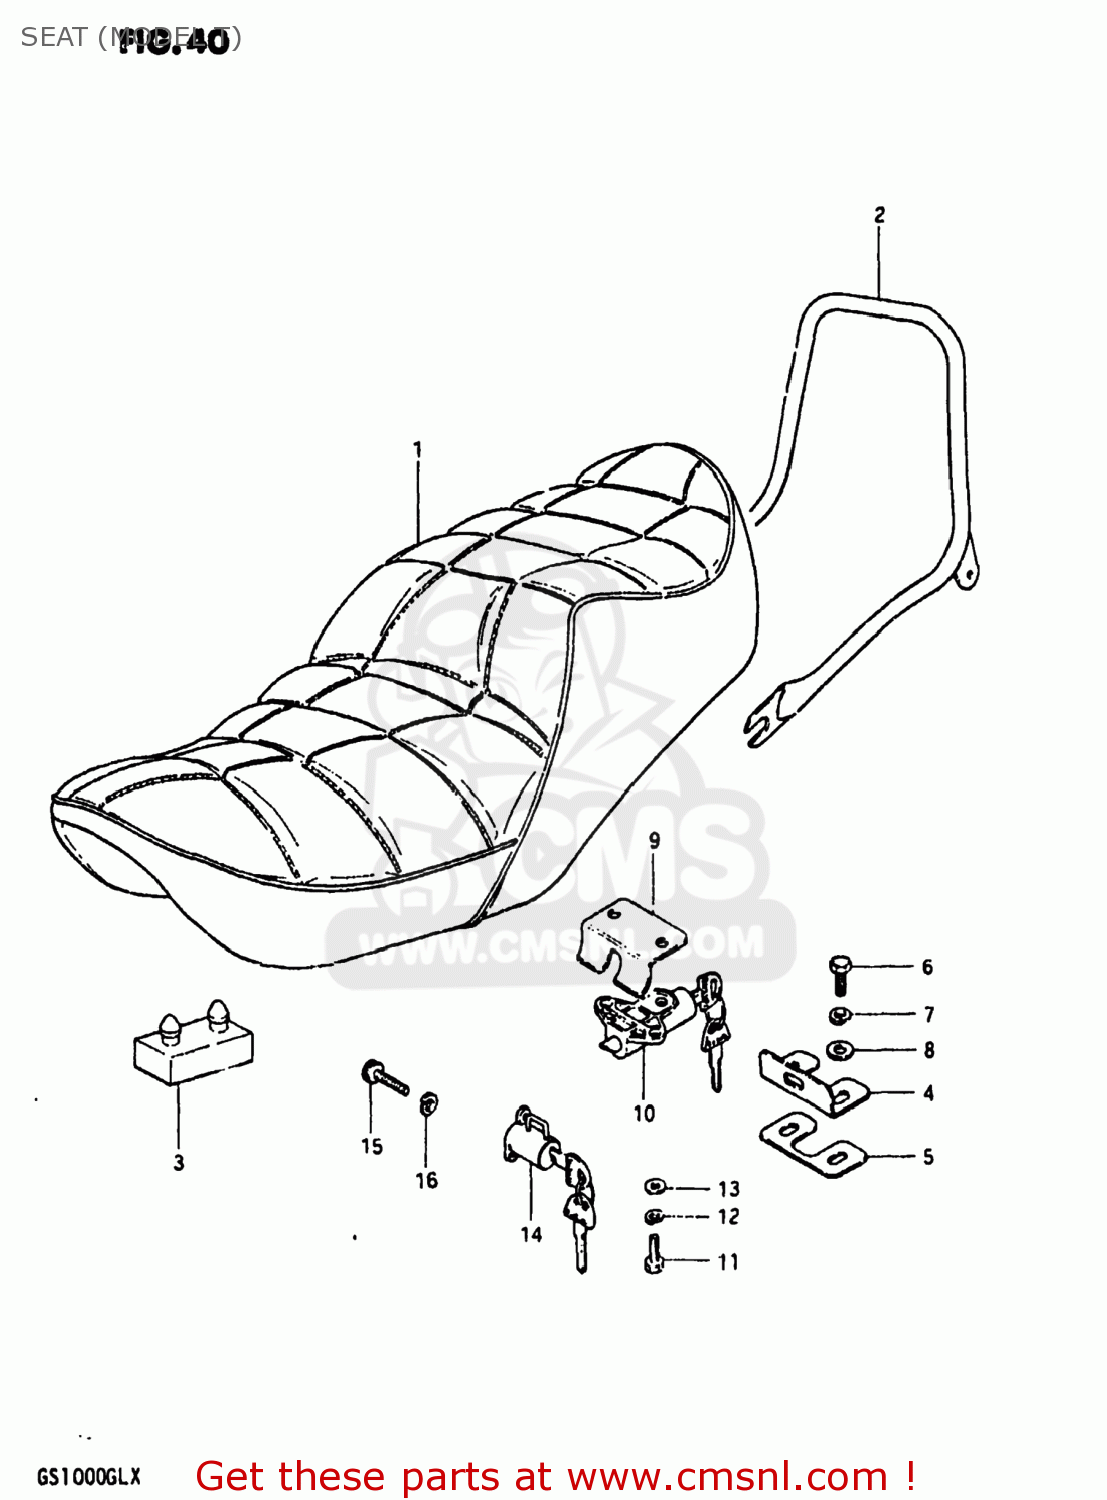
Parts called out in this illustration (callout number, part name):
1	SEAT ASSEMBLY
2	HANDLE,PILLION RIDER
3	CUSHION
4	STRIKER,SEAT LOCK
5	SHIM,SEAT LOCK STRIKER
6	BOLT, UPPER
7	LOCK WASHER
8	WASHER
9	PLATE,SEAT LOCK
10	LOCK ASSEMBLY,SEAT
11	BOLT
12	LOCK WASHER
13	WASHER 6MM
14	LOCK ASSEMBLY,HELMET
15	BOLT
16	LOCK WASHER
